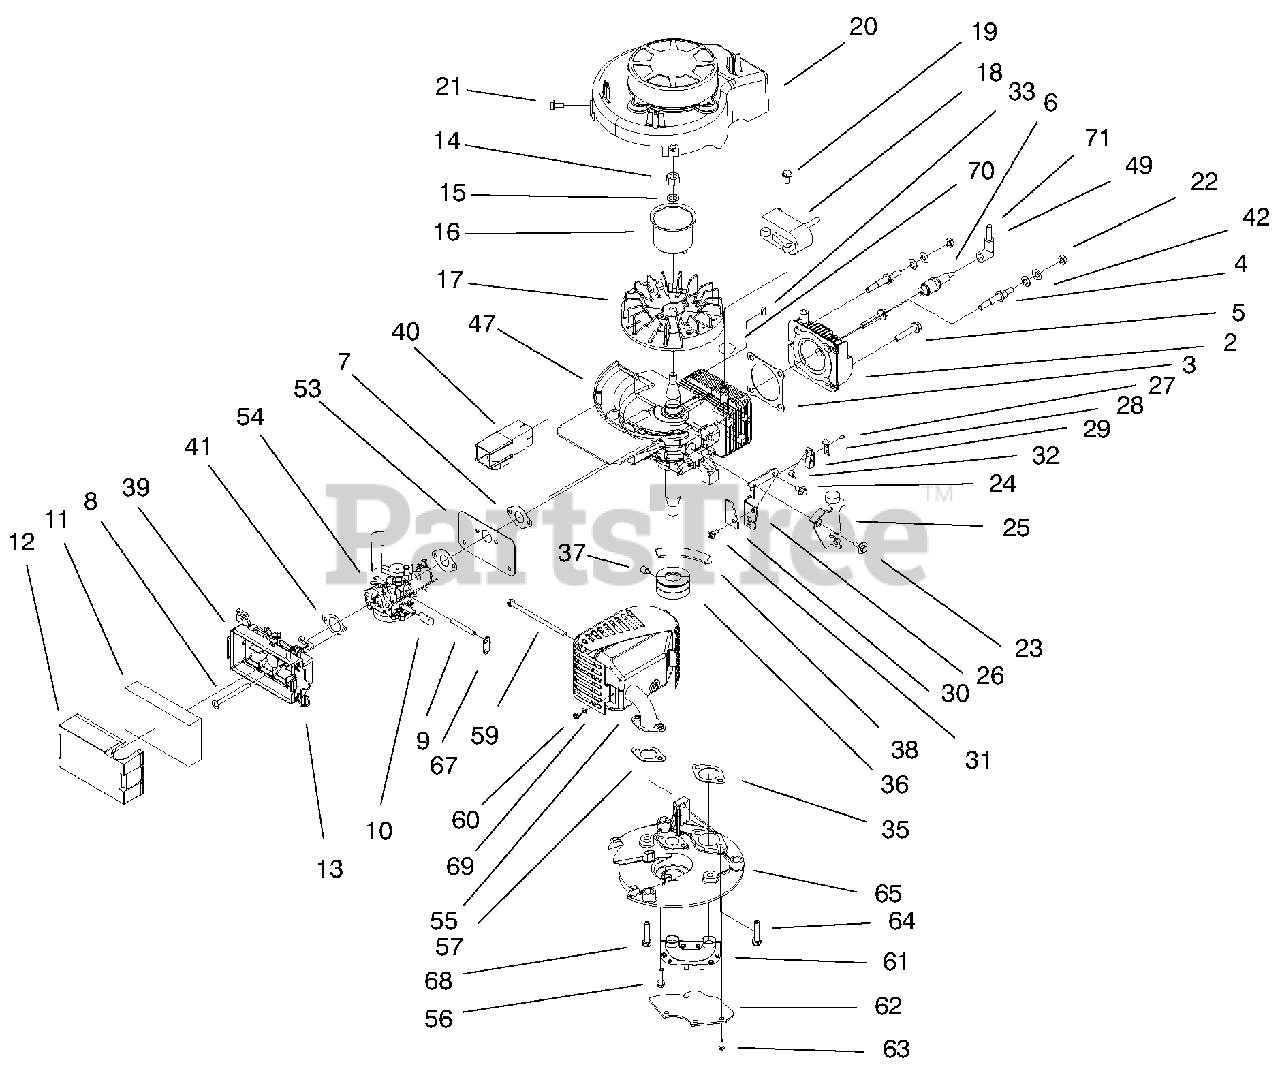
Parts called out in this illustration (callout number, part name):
3	Gasket-Head
6	Spark Plug
7	Intake Gasket
9	Primer Hose
11	Element-Air Filter
12	Cover-Air Filter
13	Retainer-Filter
15	Washer-Lock
16	Cup-Starter
17	Flywheel Machined Recoil
18	Ignition ASM
19	Screw-HWH
20	Shroud & Recoil ASM
21	Screw
22	Nut-Lock
23	Shoulder Screw Brake
24	Screw (Brake)
25	ASM-Brake Plate
26	Plate-Mount Brake
27	Rivet-Self Expand Plas
28	Strap-Insulation
29	Strap-Ground
30	Stop-Ground Strap
31	Screw-Thread Forming
32	Brake Switch Lead Wire
35	Gasket-Exhaust
36	Pulley Engine
37	Screw-Set
39	Air Filter Base ASM
41	Gasket-Filter Base
42	Washer-Lock
49	Cover & Terminal
53	Heat Shield
54	Carburetor ASM
55	Muffler & Guard
56	Screw-HWH
61	Transfer Tube
62	Cover Plate
64	Screw-HH
65	Muffler Plate Machining
67	Retainer Hose
68	Screw-HH
69	Washer-Lock
70	Tie Strap
71	Lead & Cover Asm
